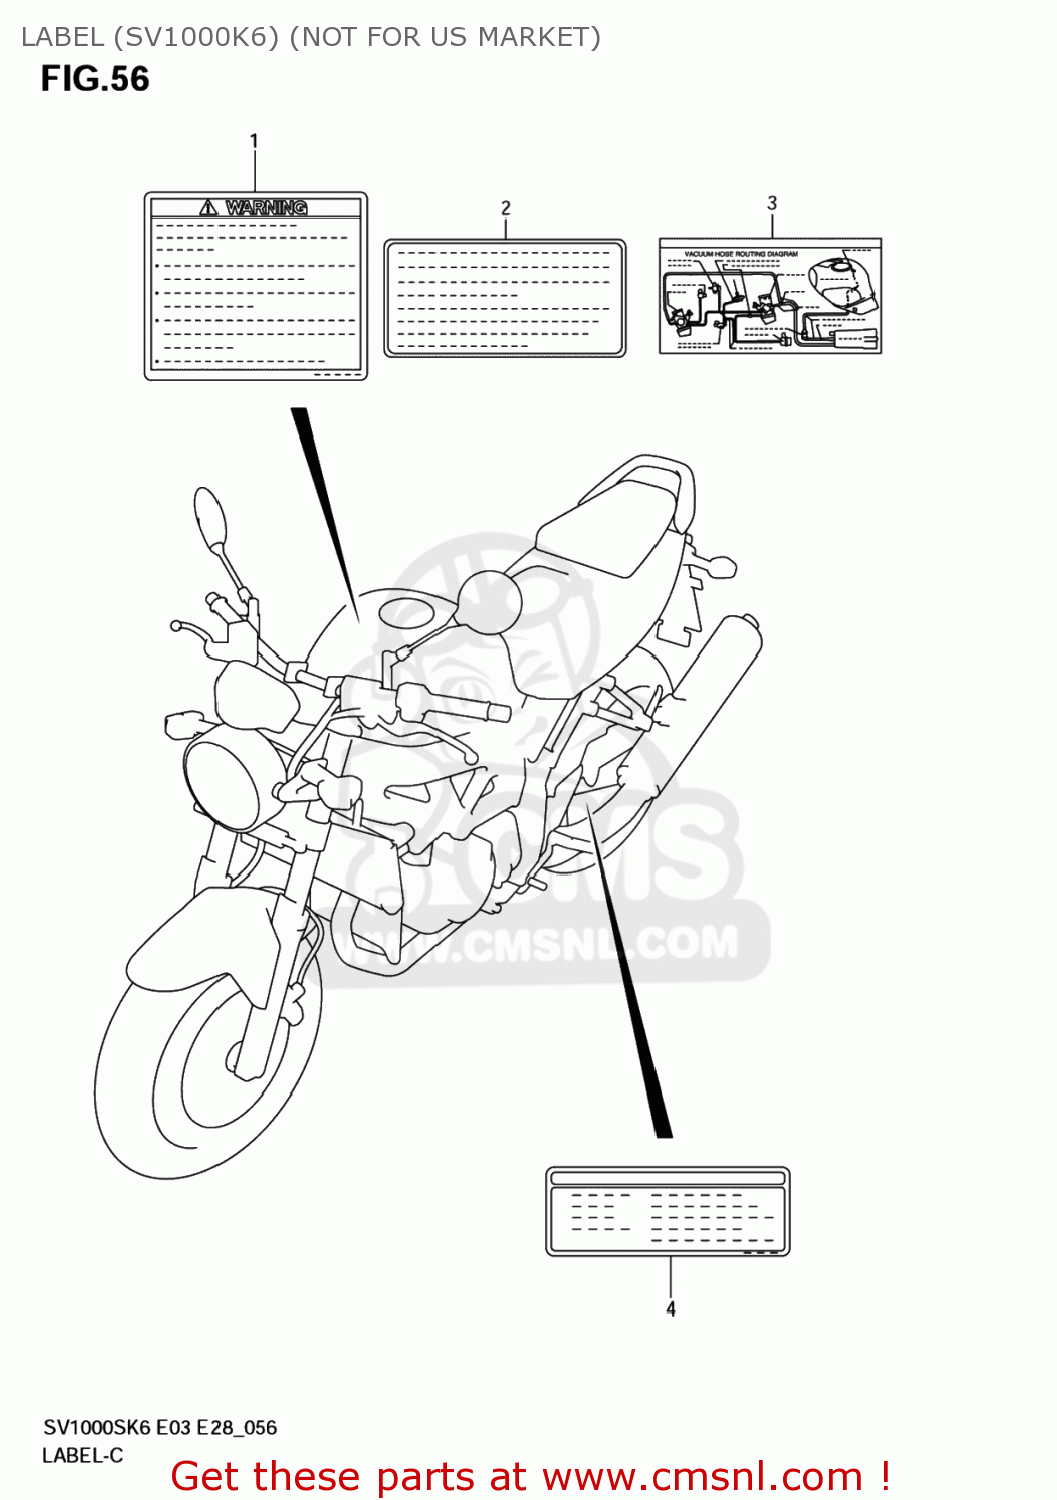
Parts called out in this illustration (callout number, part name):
1	LABEL,GENERAL WARNING
2	LABEL,MANUAL NOTICE
3	LABEL,VACUUM HOSE ROUTING
4	LABEL,TIRE INFORMATION
5	MANUAL, OWNER'S
